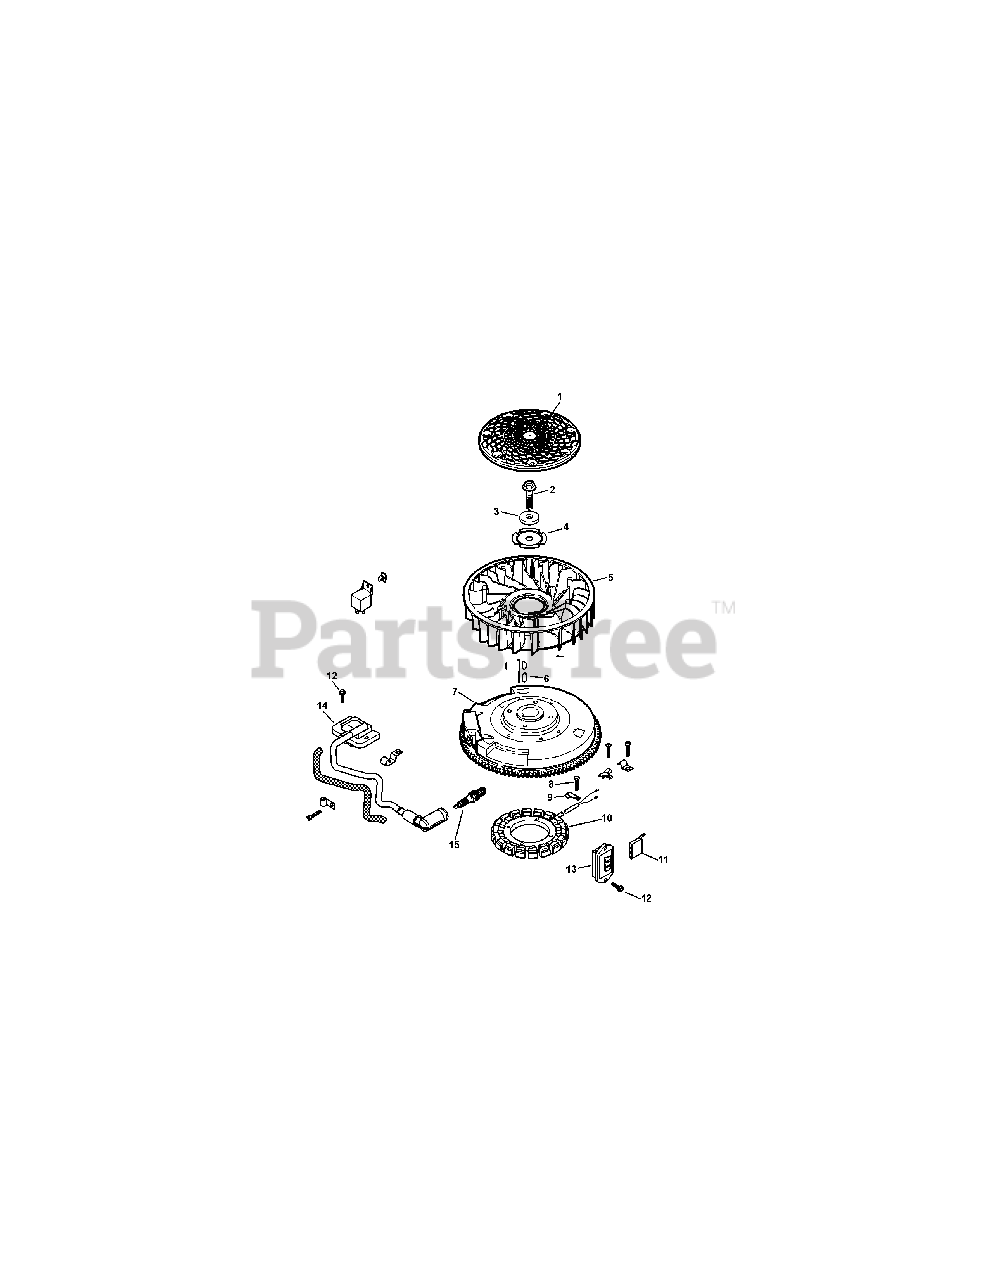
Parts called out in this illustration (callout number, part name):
2	Hex Flange Screw
4	Fan Mounting Plate
6	Straight Flywheel Key
7	Flywheel
8	Thd. Frm. Screw, M5 x 0.8 x 25
10	15 Amp Stator Kit
12	Flg. Thd. Frm. Screw, M5 x .8 x 20
13	Regulator/Rectifier
14	Ignition Module (CDI Fixed)
15	Spark Plug
